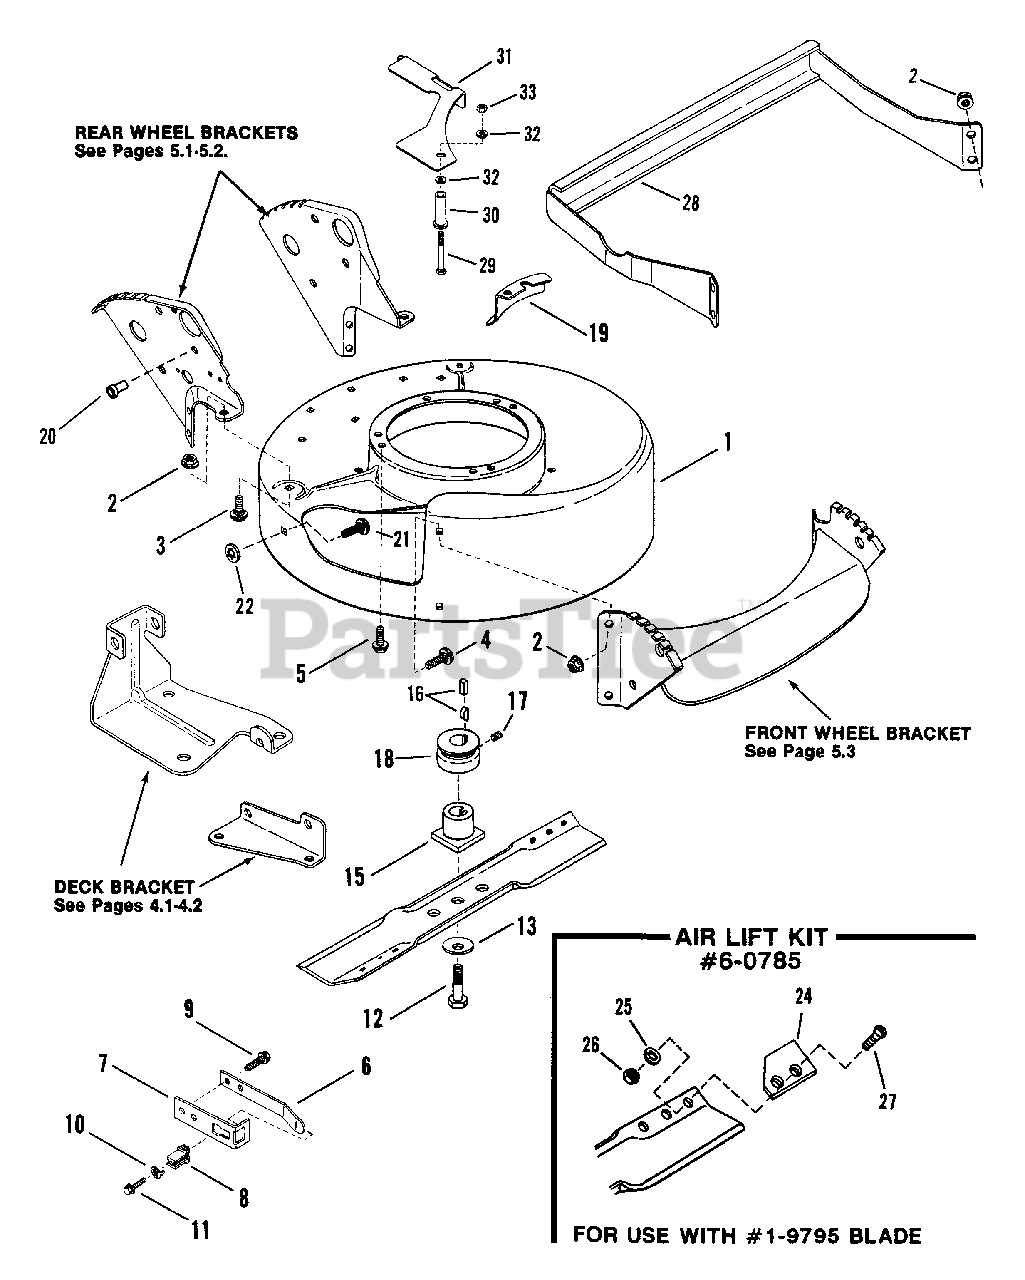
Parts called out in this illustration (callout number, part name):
1	DECK, Mower
2	NUT, 5/16-18 Hex Flange Lock
3	BOLT, 5/16-18 x 1/2" Short Neck Carriage
4	BOLT, 5/16-18 x 1-1/8" Short Neck Carriage
5	SCREW, 3/8-18 x 1" Self-Tapping (Engine Mounting)
6	SPRING, Wheel Bracket Type Interlock
7	BRACKET, Wheel Bracket Type Interlock
8	INSULATOR, Interlock
9	SCREW, 1/4-20 x 1/2" Self-Tapping
10	WASHER, #8 Tab Internal Tooth Lock
11	SCREW, #8-18 x 3/4" Hex Machine
12	SCREW, 3/8-24 x 2" Hex Head Cap (Gr. 5)
13	WASHER, Cone
15	HUB, Blade Drive
16	KEY, 3/16 x 5/8" Woodruff (Briggs)
17	SCREW, 5/16-18 x 5/16" Hex Socket Set
18	PULLEY, Engine (Briggs)
19	SHIELD, Belt Opening Cover (Push Models Only)
20	BUSHING, Interlock Wire
21	BOLT, 5/16-18 x 3/4" Short Neck Carriage
22	RETAINER, 5/16 Bolt
24	LIFT, Air
25	WASHER, 5/16 Internal Tooth Lock
26	NUT, 5/16-24 Hex
27	SCREW, 5/16-24 x 21/32" Machine
28	STRUCTURE, Fender (European Models Only)
29	BOLT, 5/16-18 x 2-1/4" Hex Flange Lock
30	BUSHING
31	COVER, Belt (European Models Only)
32	WASHER, 5/16 Split Lock
33	NUT, 5/16-18 Hex
